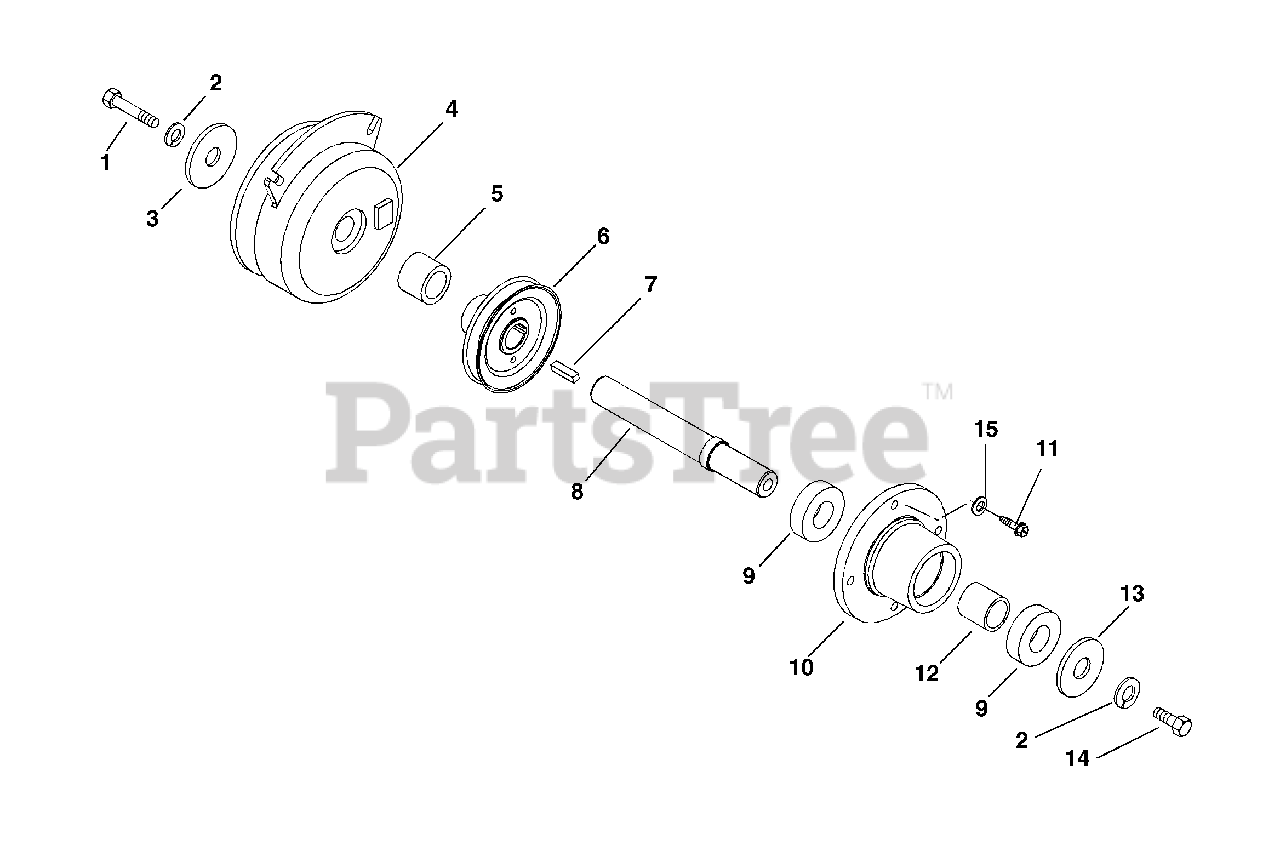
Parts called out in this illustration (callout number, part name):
1	BLT-HEX .44-20X1.50 GR5 YWZC
1	BLT-HEX .44-20X2.50 GR5 YWZC
2	@WSHR-LK .44X.109 REG YWZC
3	WSHR-FL-STL .469X2.00X.25 YWZC
4	CLUTCH, ELECTRIC - WARNER
4	ELECTRIC CLUTCH/BRAKE (3.4AMP)
5	SPACER 1.004X1.500X.740
6	SHEAVE, JACKSHAFT 4.50
7	KEY-SQ .25X1.0X.25 SAE 8630
7	KEY-SQ .25X.625X.25 SAE 8630
8	SHAFT - JACK
9	BRG-BALL .984X2.04X.59
10	HOUSING, TRANS SPNDL, BLACK
11	@SCR-TAP .31-18X.75 HWH TR YWZ
12	SPACER 1.0X1.253X1.26
13	WSHR-FL-STL.463X1.375X.25 YWZC
14	BLT-HEX .44-20X1.00 GR5 YWZC
15	WSHR-FL-STL .328X1.0X.094 YWZC
